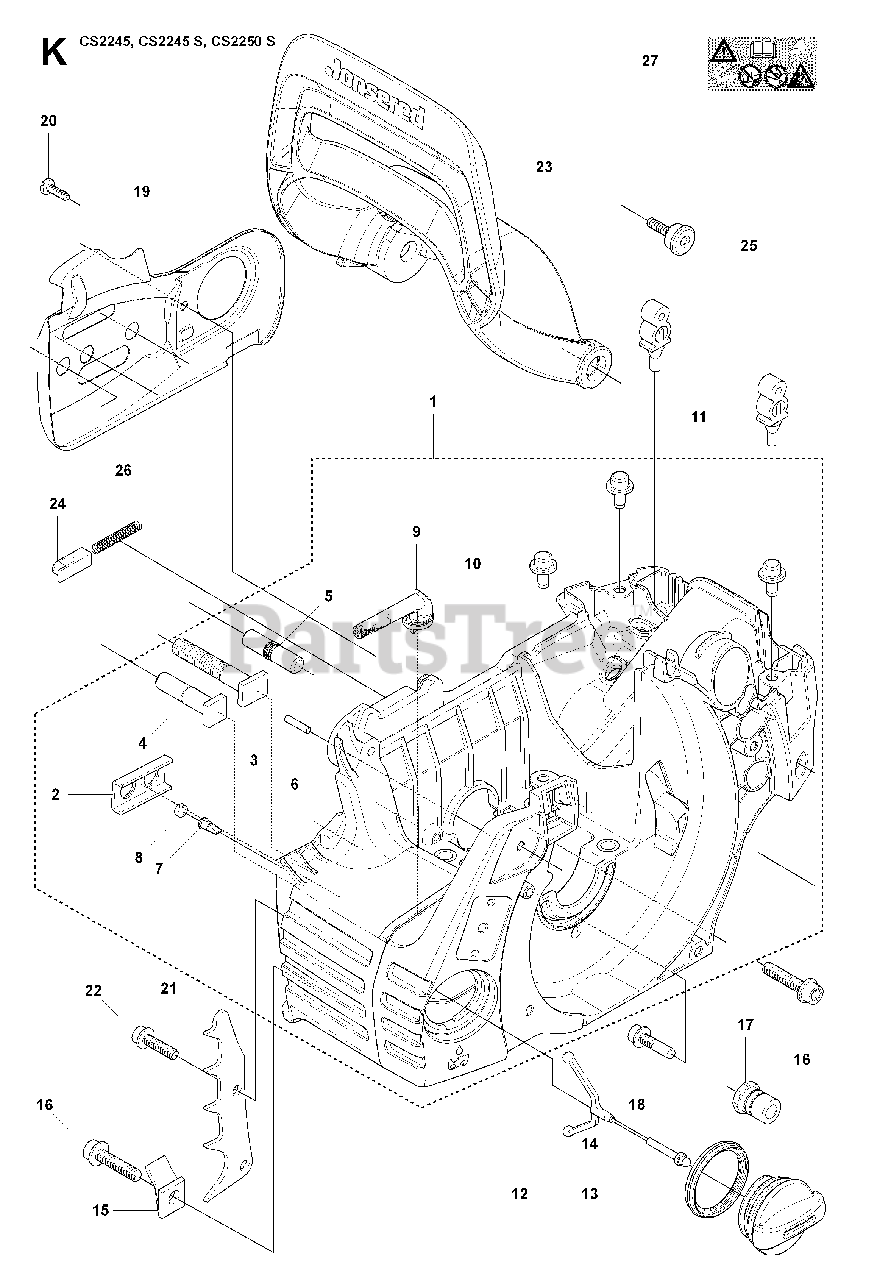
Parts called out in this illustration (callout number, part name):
1	CRANKCASE
2	STIFFENING PLATE
4	BAR BOLT (X2)
7	VALVE-CHECK (DUCKBILL)
8	PLUG
9	OIL SCREEN
10	GUIDE PEN
11	SUPPORT
12	TANK CAP ASSY
13	SEALING
15	CHAIN CATCHER
16	SCREW IHSCFT
17	LATERAL SUPPORT
18	SCREW IHSCFT
19	CHAIN GUIDE PLATE
21	FELLING DOG
23	HAND GUARD
25	SCREW
26	LOCK SPRING
